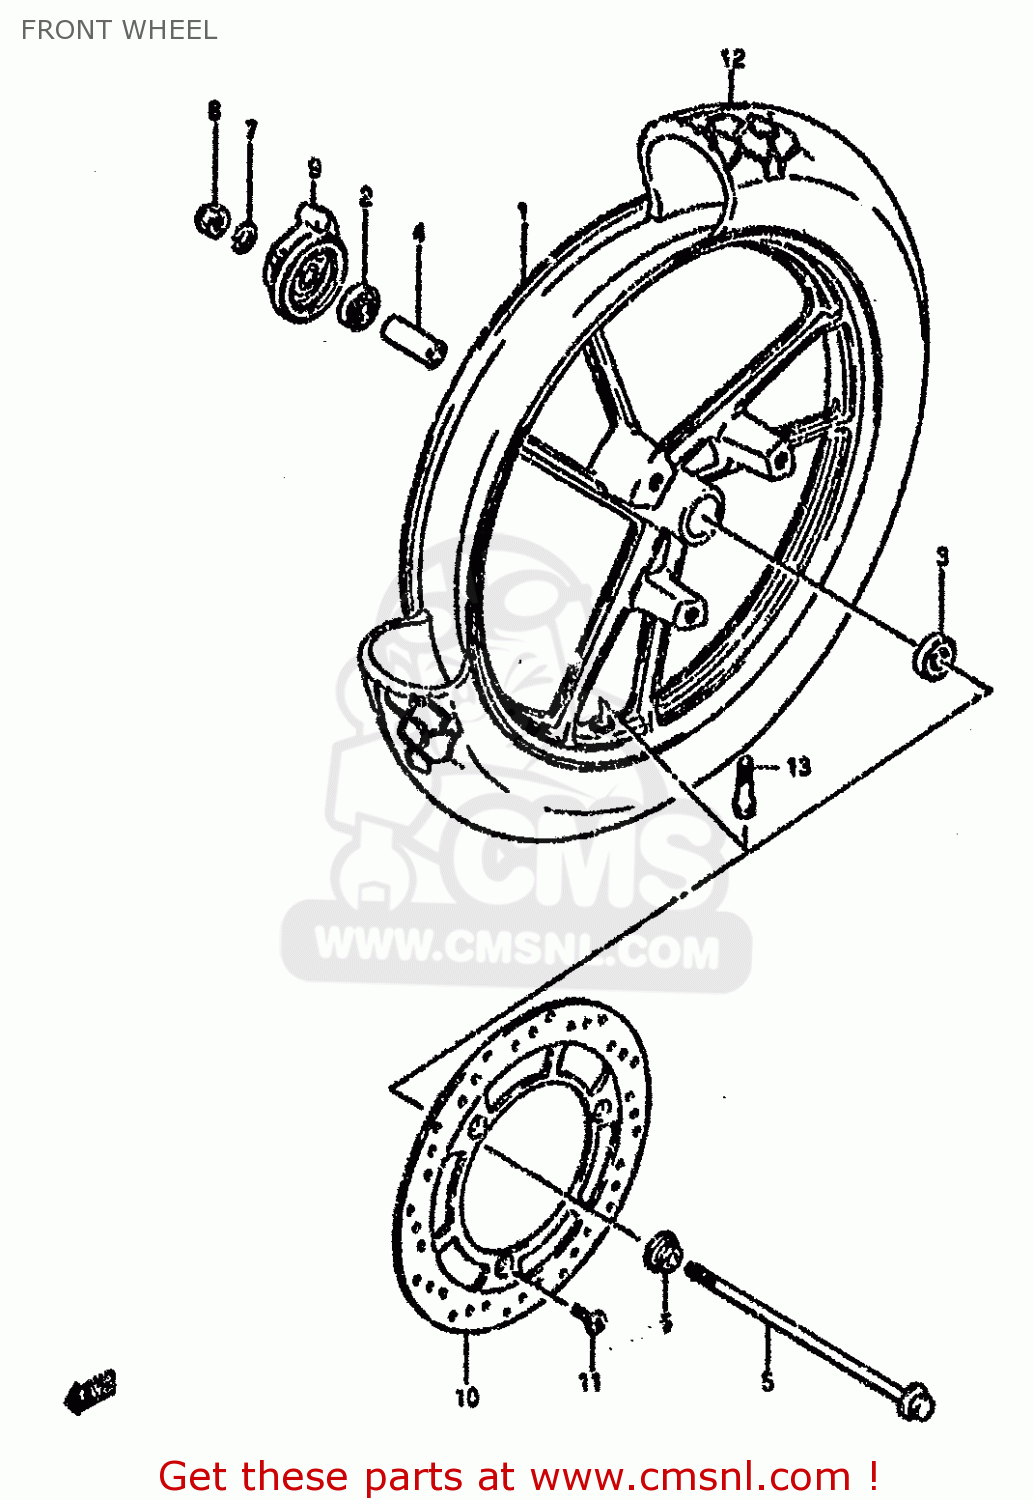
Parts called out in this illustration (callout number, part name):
1	WHEEL, FRONT, MT 1.85*16 (BLACK)
2	BEARING
3	BEARING (12X32X10)
4	SPACER, FRONT HUB (12.6*19*48)
5	AXLE, FRONT
6	SPACER,FR AXLE,L
7	WASHER
8	NUT
9	BOX ASSY,SPEEDOMETER GEAR
10	DISC,FR BRAKE
11	BOLT,BRAKE DISC
12	TIRE, T/L FRONT (80/100-16)
13	VALVE,TIRE
